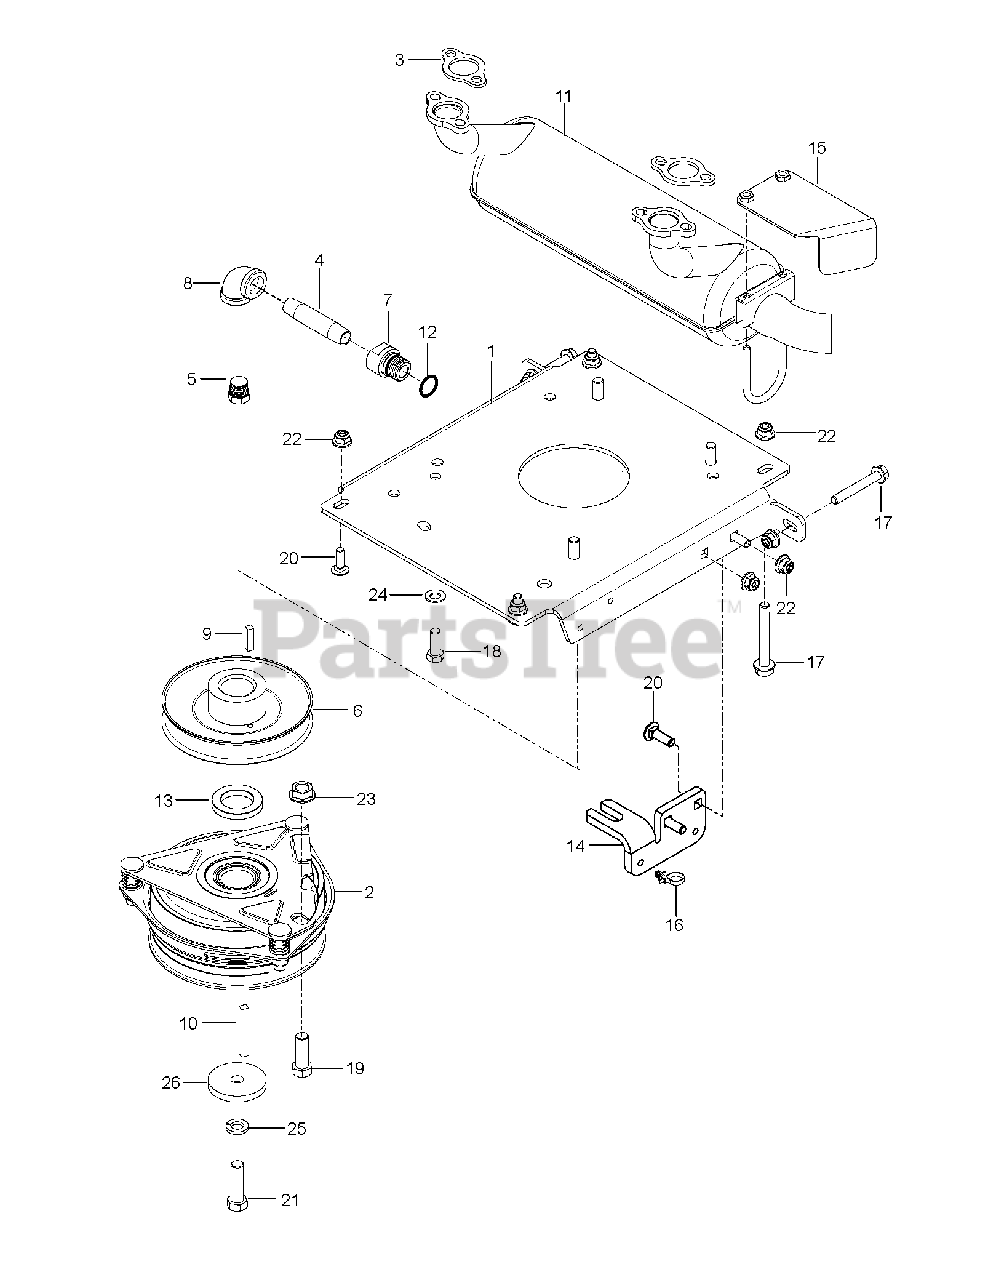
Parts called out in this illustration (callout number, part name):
1	PLATE.PNT.ENGINE.PZ/PZT.EDIP
2	CLUTCH, 150 FT/LBS
3	GASKET.EXHAUST.KAWASAKI
4	PIPE NIPPLE 3/8 X 3
5	PLUG, DRAIN 3/8 NPTF
6	PULLEY, ENGINE
7	ADAPTER, OIL DRAIN
8	90 DEG.ELBOW 3/8NPT
9	KEY 1/4 SQ X 1.0
10	KEY 1/4 SQ X 2
11	MUFFLER.26HP.KAW.FX651V-730V
13	SPACER, .25 X 1.135 I.D.
14	STOP, CLUTCH, OGURA
15	SHIELD MUFFLER
16	TIE WRAP, 8-3/8", W/CLIP
17	HHFS 5/16-18 X 2.25 GD 5
18	HCS 3/8-16X1.GRD.5.ZD
19	HCS 7/16-14 X 1-1/4 GR 5 ZD
20	RHSNB 5/16C X 1
21	CLUTCH BOLT7/16-20X1.5GR5.96HR
22	5/16-18 NYLOC FLANGE NUT
23	NUT 7/16C WHIZ
24	WASHER, 3/8 DISC SPRING SPEC
25	WASHER 7/16 LOCK
26	BLADE WASHER
